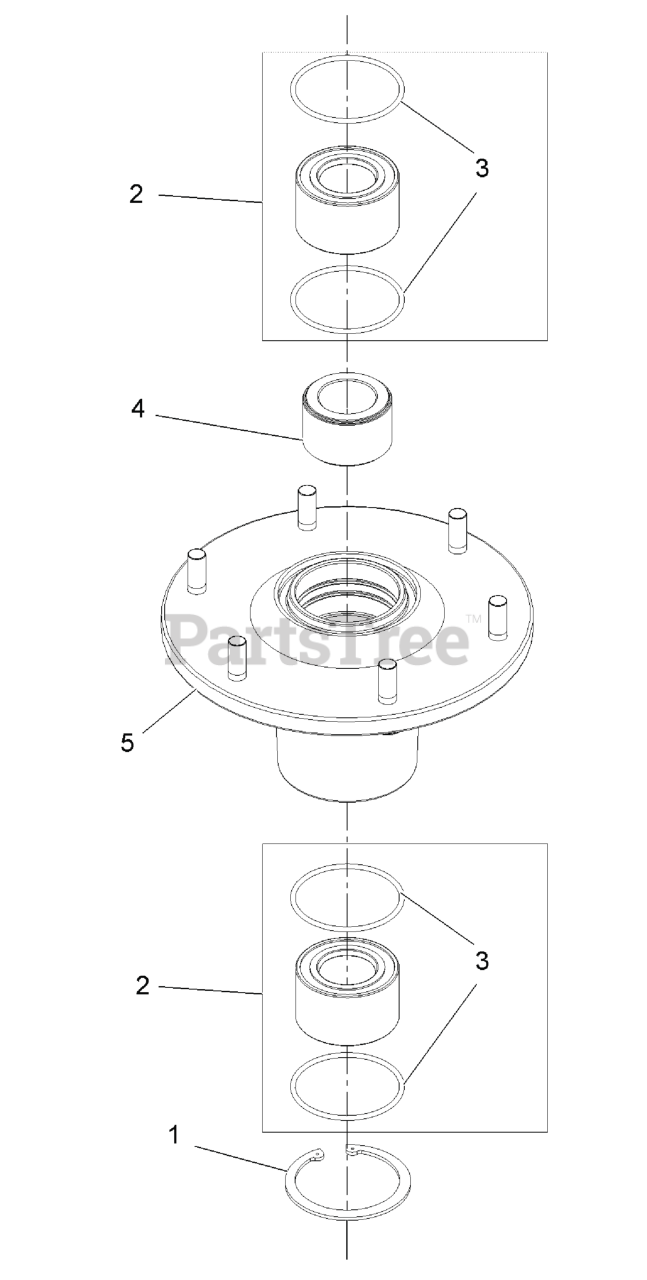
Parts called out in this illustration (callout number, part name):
1	RING-RETAINING
2	ASM, BEARING W/ORINGS
4	SPACER,BEARING
5	ASM,HOUSING W/STUDS
